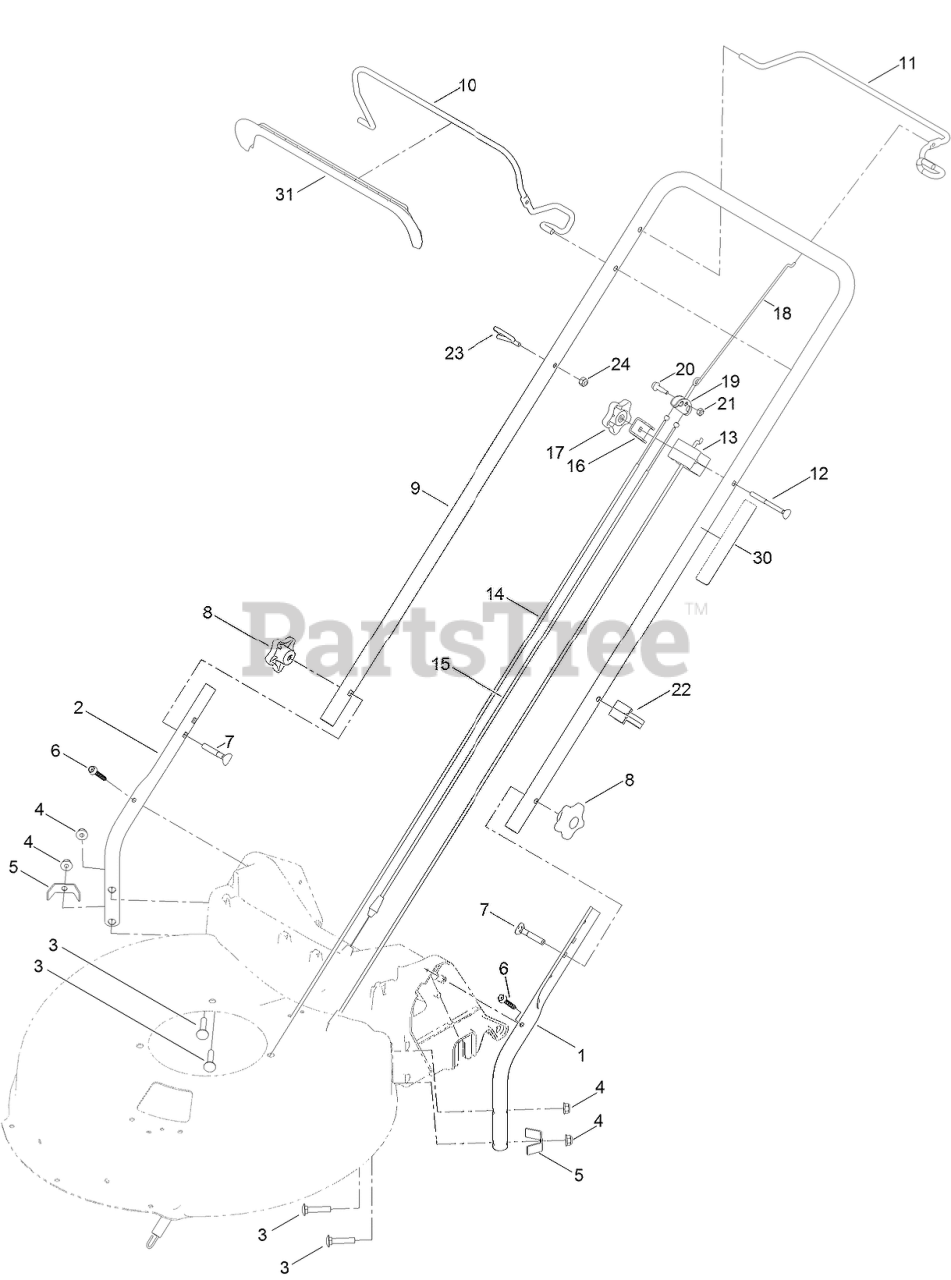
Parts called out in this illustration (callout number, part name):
1	HANDLE-LOWER, LH
2	HANDLE-LOWER, RH
3	BOLT-CARR
4	NUT-FLANGE, NI
5	BRACKET-CHUTE
6	SCREW-FLANGE, SERRATED
7	SCREW-HANDLE
8	KNOB-HANDLE
9	HANDLE-UPPER
10	BAIL-BRAKE
11	BAIL-TRACTION
12	SCREW-HANDLE
13	CABLE-BRAKE
14	CABLE-TRACTION, FRONT
15	CABLE-TRACTION, REAR
16	CLAMP-CABLE
17	KNOB-HANDLE, LOCKING
18	LINKAGE, EQUALIZER
19	YOKE-CABLE
20	SCREW-SHOULDER
21	NUT-LOCK, NI
22	GUIDE-CABLE
23	GUIDE-ROPE
24	NUT-LOCK, NI
30	DECAL-TRACTION, ADJUST
31	COVER-BAIL
